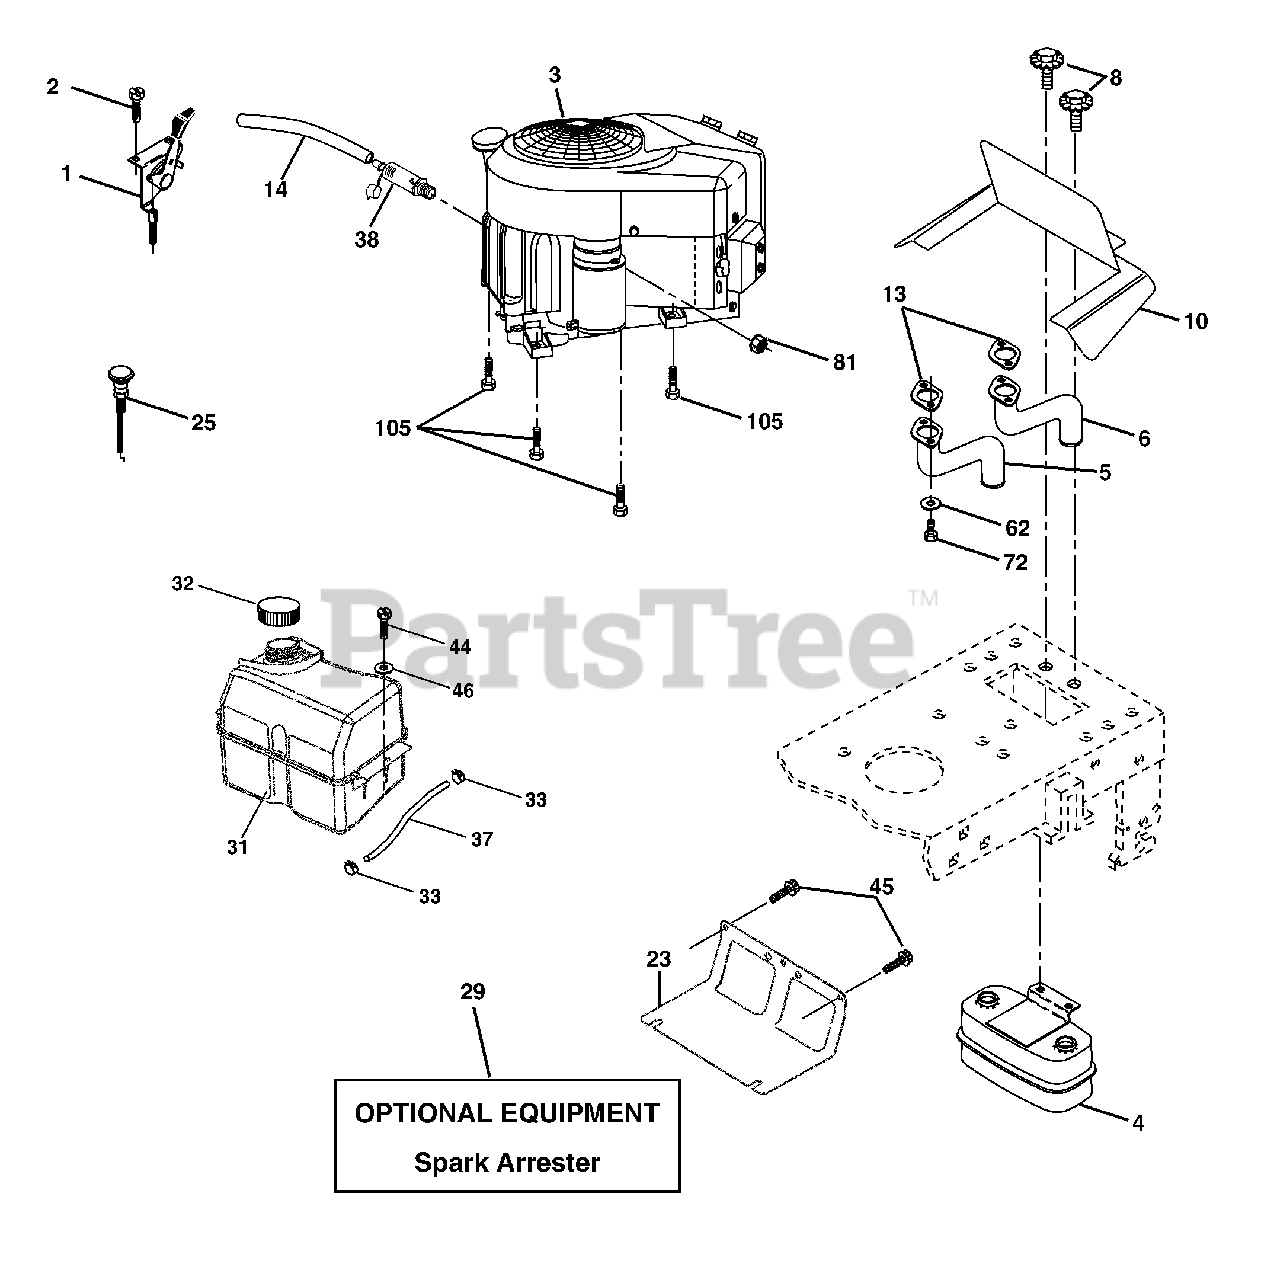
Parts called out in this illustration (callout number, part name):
1	Control Throt /Ch Flag
2	Screw Hex Thd Cut 1/4-20x1/2
4	Muffl er
5	Exhaust Tube LH
6	Exhaust Tube RH
8	Bolt 5/16-18unc x 3/4
10	Shield Muffler
13	Gasket
14	Tube Drain Oil Easy
23	Shield Browning/Debris Guard
25	Control Choke
29	Arrestor Spark
31	Tank Fuel
32	Cap Asm Fuel W/sym Vented
33	Clamp Hose Blk
37	Line Fuel 20"
38	Plug Drain Oil Easy
41	Stem Fuel Tank
44	Screw Hexwsh Thdrol 1/4-20x3/4
45	Screw Hex Wsh Thdrol 3/8-16
46	Washer 9/32 X 7/8 X 16ga
62	Washer Lock 5/16
72	Screw Hex Hd Cap 5/16-18 x 3/4
81	Nut Keps Hex 1/4-20 Unc
105	Screw Thdrol 3/8-16x1-1
112	Bushing, Outlet
